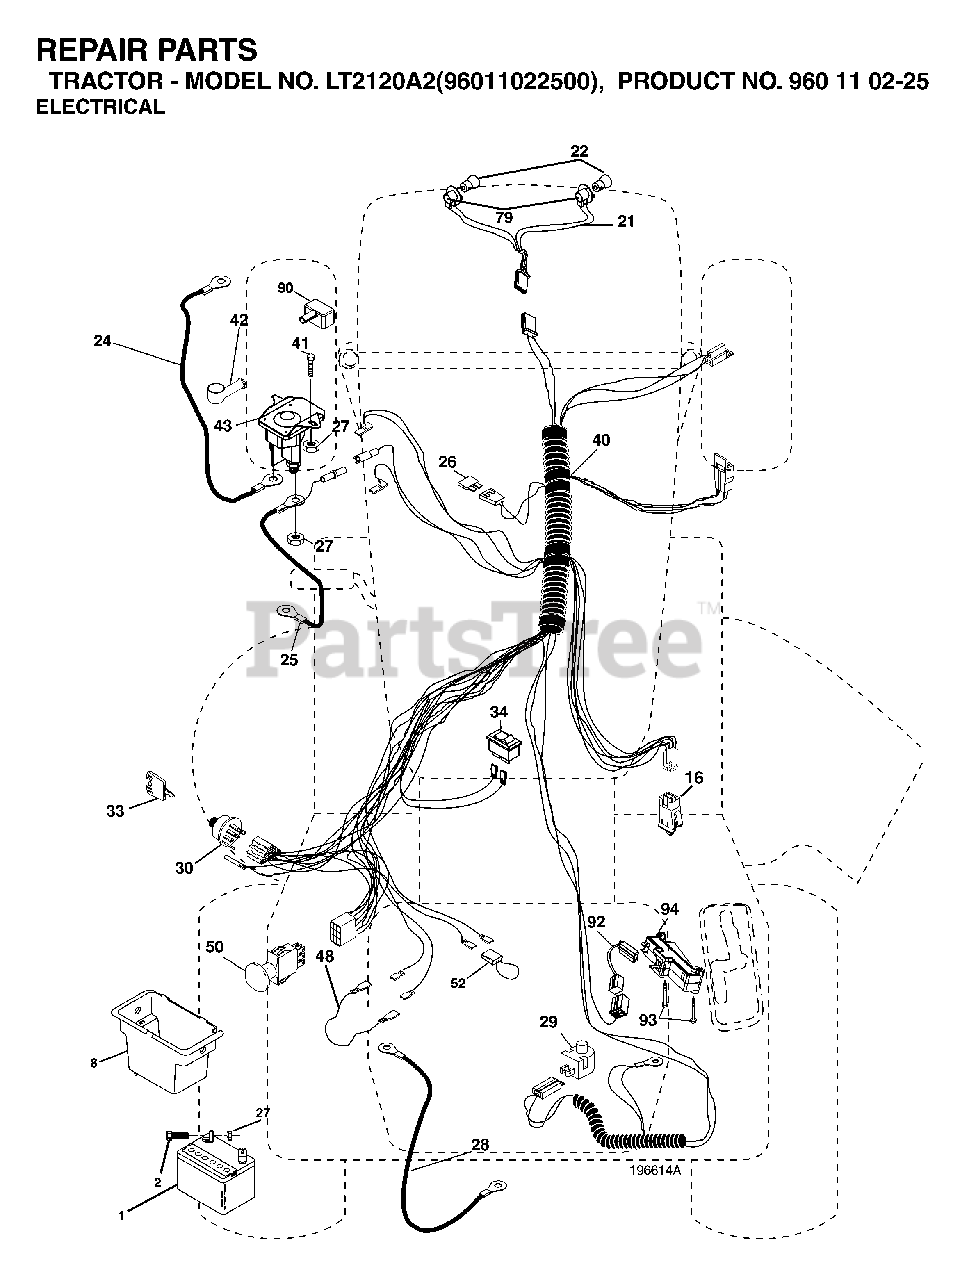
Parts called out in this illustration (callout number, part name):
1	BATTERY 12V .35 AMP
8	BOX.BATTERY.FENDER
16	SWITCH INTERLOOK PUSH-IN
21	HARNESS.W/LIGHT SOCKET
22	LIGHTBULB
24	BATTERY CABLE GT
25	CABLE BATTERY
26	FUSE 20AMP
27	NUT
28	CABLE T
29	SWITCH.SEAT.DP W/RAMPS
30	SWITCH.IGN.DELTA.W.LGH.ROS
33	KEY MLD GEN DELTA
34	SWITCH LT
41	SCREW
42	TERMINAL COVER
43	SOLENOID.W/BRASS.PLUNG
50	PTO SWITCH
52	WIRE PROTECTION LOOP
79	BULB HOLDER ASM.
90	COVER TERMINAL
92	HARNESS.PIGTAIL.CONSLE
93	SCREW.PLASTITE
94	MODULE.REVERSE.ROS
